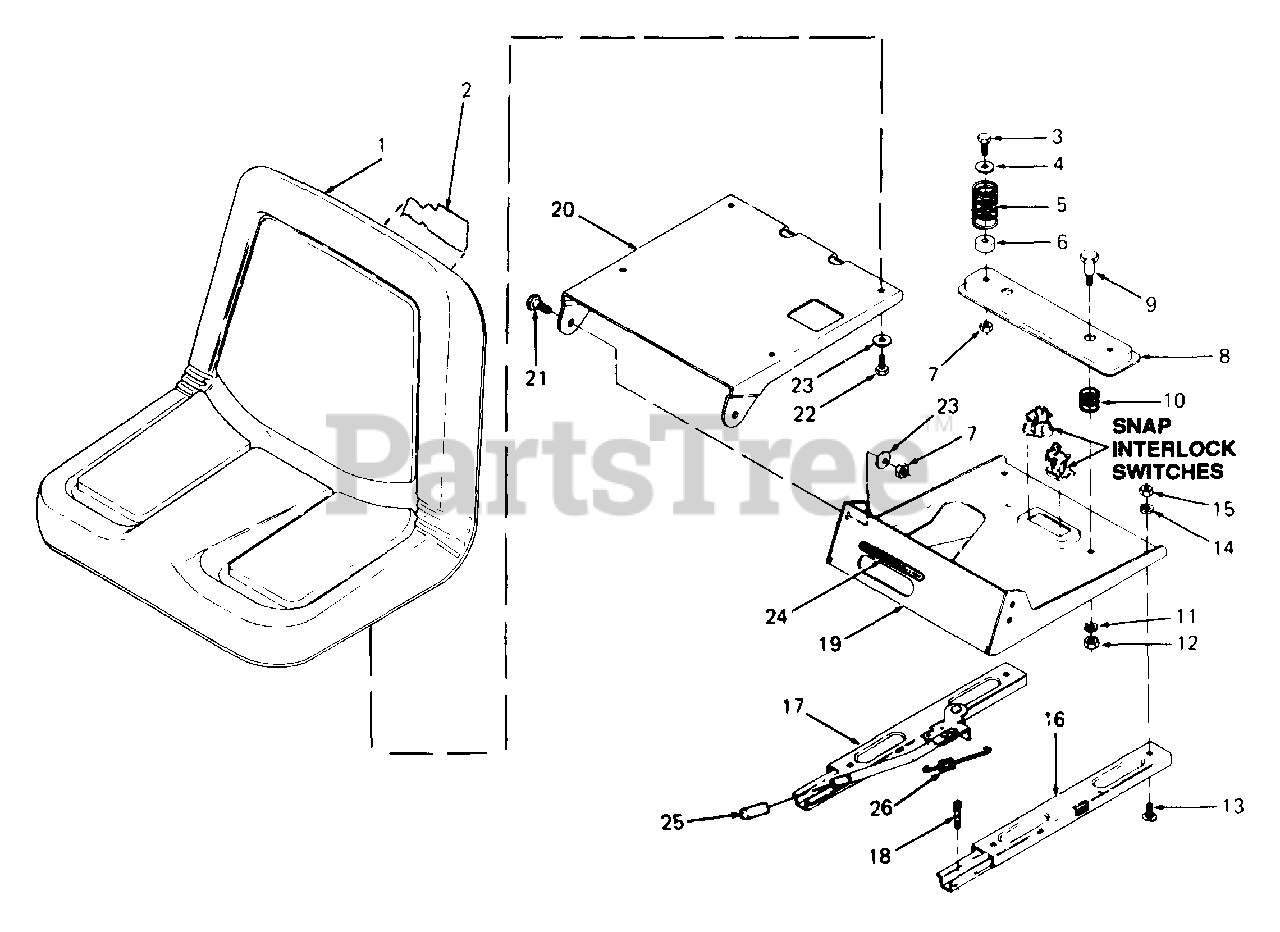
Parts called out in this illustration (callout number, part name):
1	Seat
2	Graphic, Made in USA
3	Screw, Hex Cap, 5/16-18 X .88 Lg GR5
4	Washer, Flat, .344 X .875 X .06 Thk
5	Spring, Comp, 1.28 OD X 2.18 Lg
6	Bushing, .930 OD X .50 Lg
7	Nut, Hex Center Lock, 5/16-18 GR5
10	Spring, Comp, 1.00 OD X .86 Lg
11	Washer, Lock, 3/8
12	Nut, Hex, 3/8-16 GR5
13	Bolt, Sht Nk Carriage, 5/16-18 X .62 Lg
14	Washer, Lock, 5/16
15	Nut, Hex, 5/16-18 GR5
16	Slide, Seat - LH
17	Adjuster, Manual Seat - RH
18	Screw, Socket Hd Cap, 5/16-18
22	Screw, Hex Cap, 5/16-18 X .75 Lg GR5
23	Washer, Bell, .345 X .88 X .060 Thk
24	Label, Seat Adjustment
25	Cover, Handle
